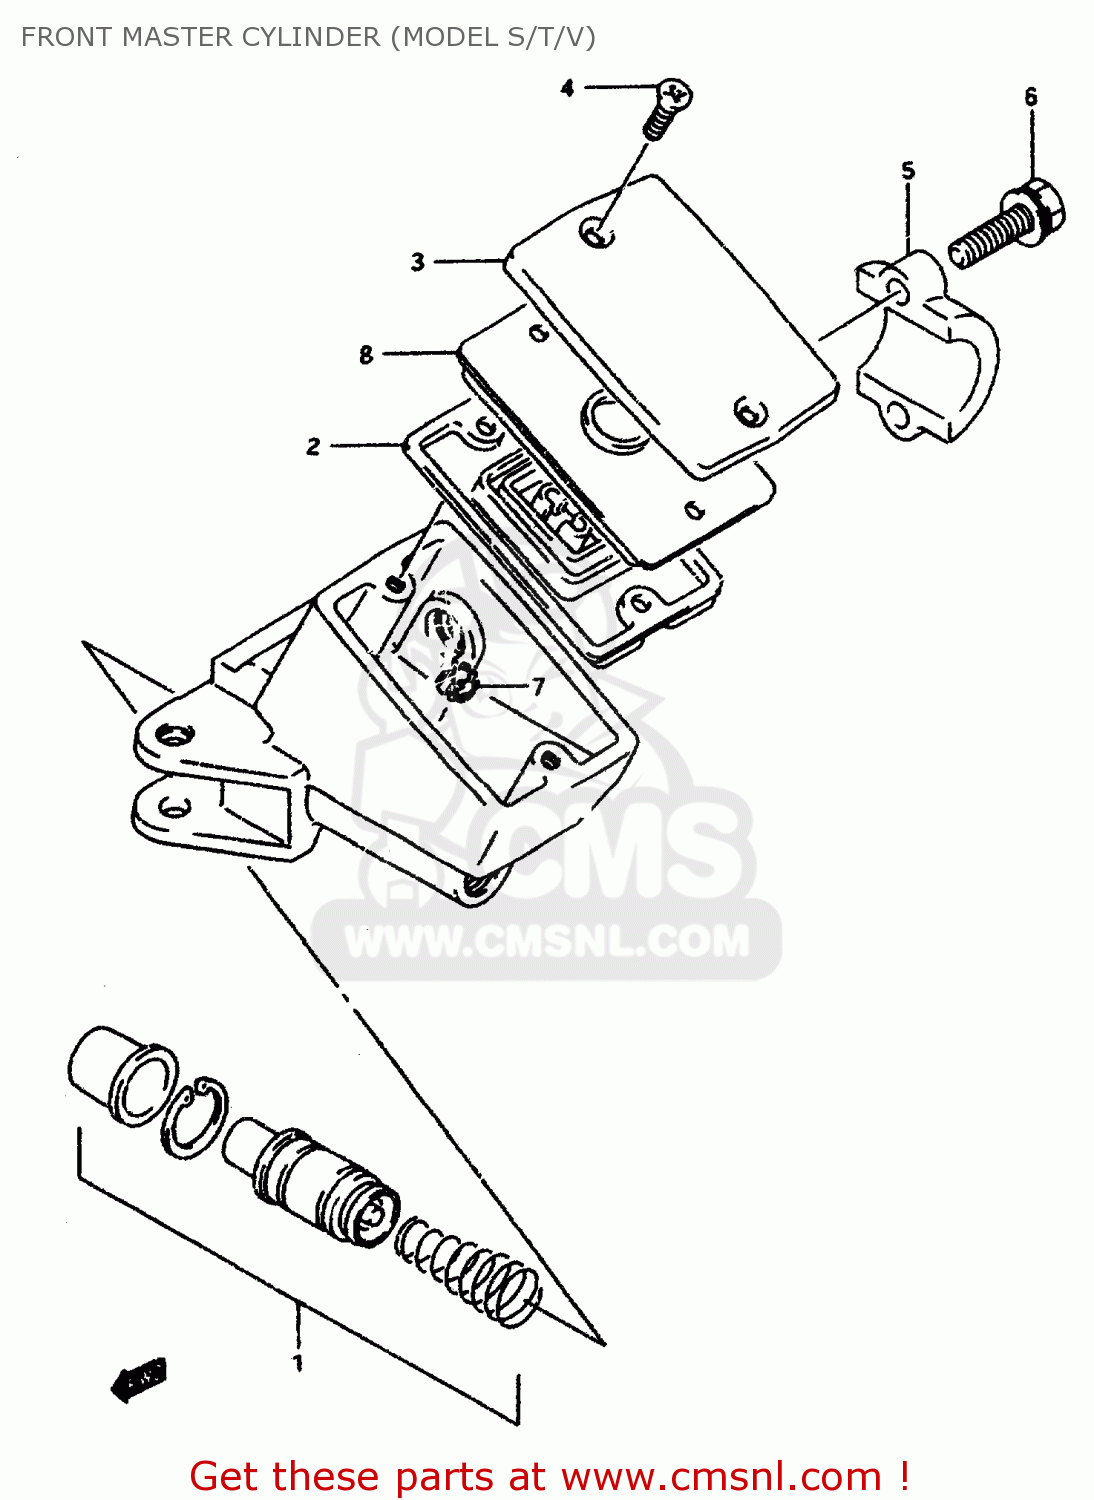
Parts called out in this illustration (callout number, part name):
1	PISTON & CUP SET
2	3
3	CAP
4	SCREW
5	HOLDER
6	BOLT(6X25)
7	PROTECTOR
8	PLATE,DIAPHRAGM
